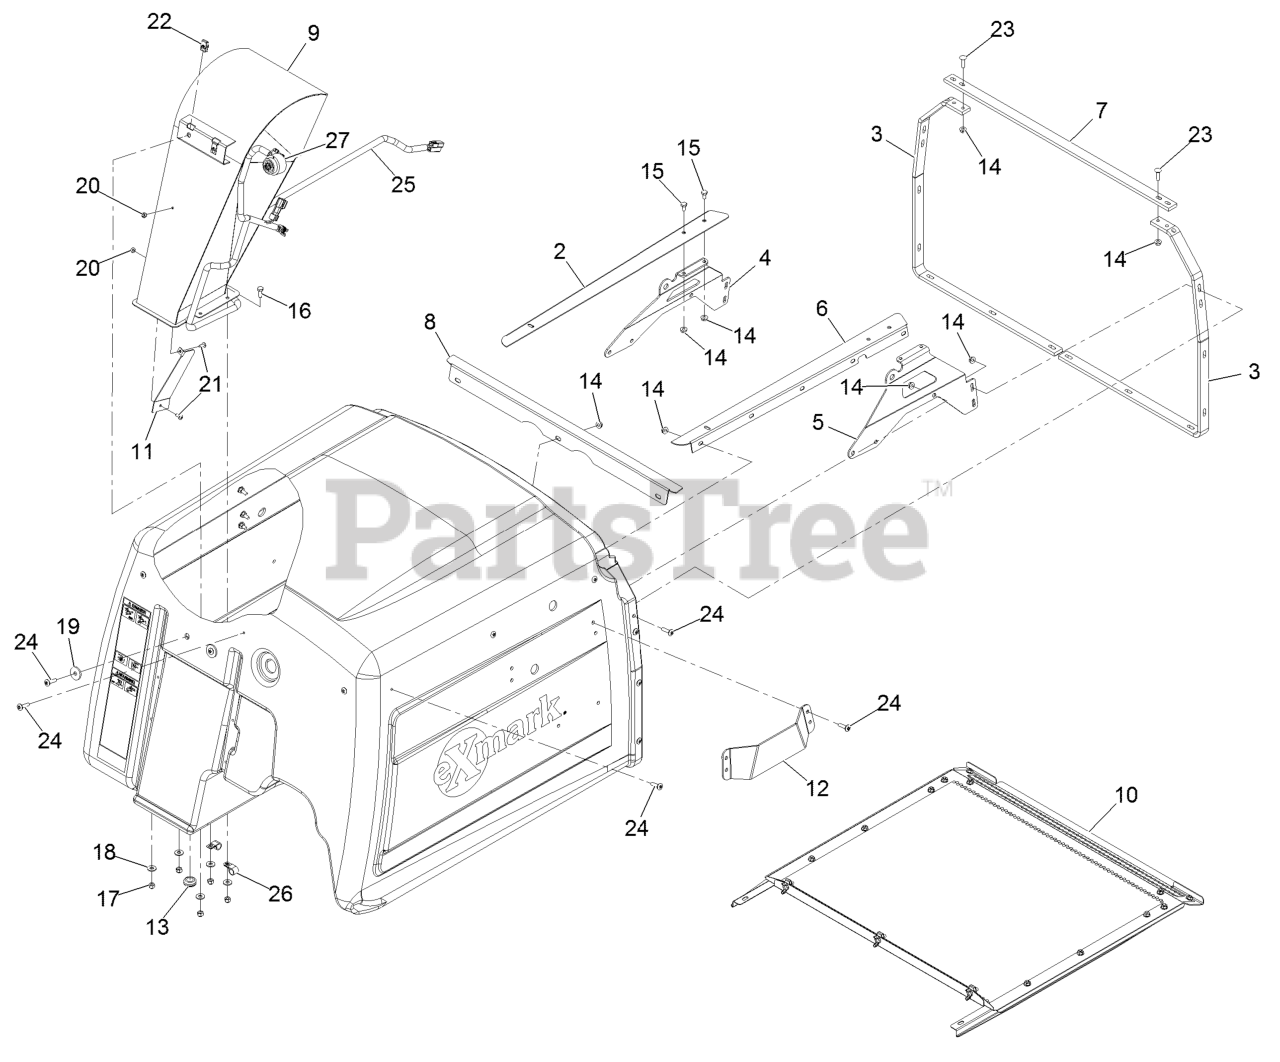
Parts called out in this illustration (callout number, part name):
2	ANGLE-SCREEN TRACK, RH
3	REINFORCEMENT-HOPPER
4	BRACE-DOOR PIVOT, RH
5	BRACE-DOOR PIVOT, LH
6	ANGLE-SCREEN TRACK, LH
7	BRACKET-FRAME CONNECT
8	CHANNEL-SCREEN, FRONT
10	HOPPER SCREEN ASM
11	DEFLECTOR-DISCHARGE CHUTE
12	PLATE-GUARD
13	GROMMET
15	SCREW-HH
16	SCREW-HH
17	NUT-LOCK, NI
18	WASHER-FLAT
20	NUT-LOCK, NI
21	SCREW-PTH
22	Nut-Retainer-Panel 1/4-20
23	SCREW-CARR
24	SCREW-TTH
25	HARNESS-WIRE, HOPPER
26	CLIP-LOOM
27	ALARM-TONE, DUAL
